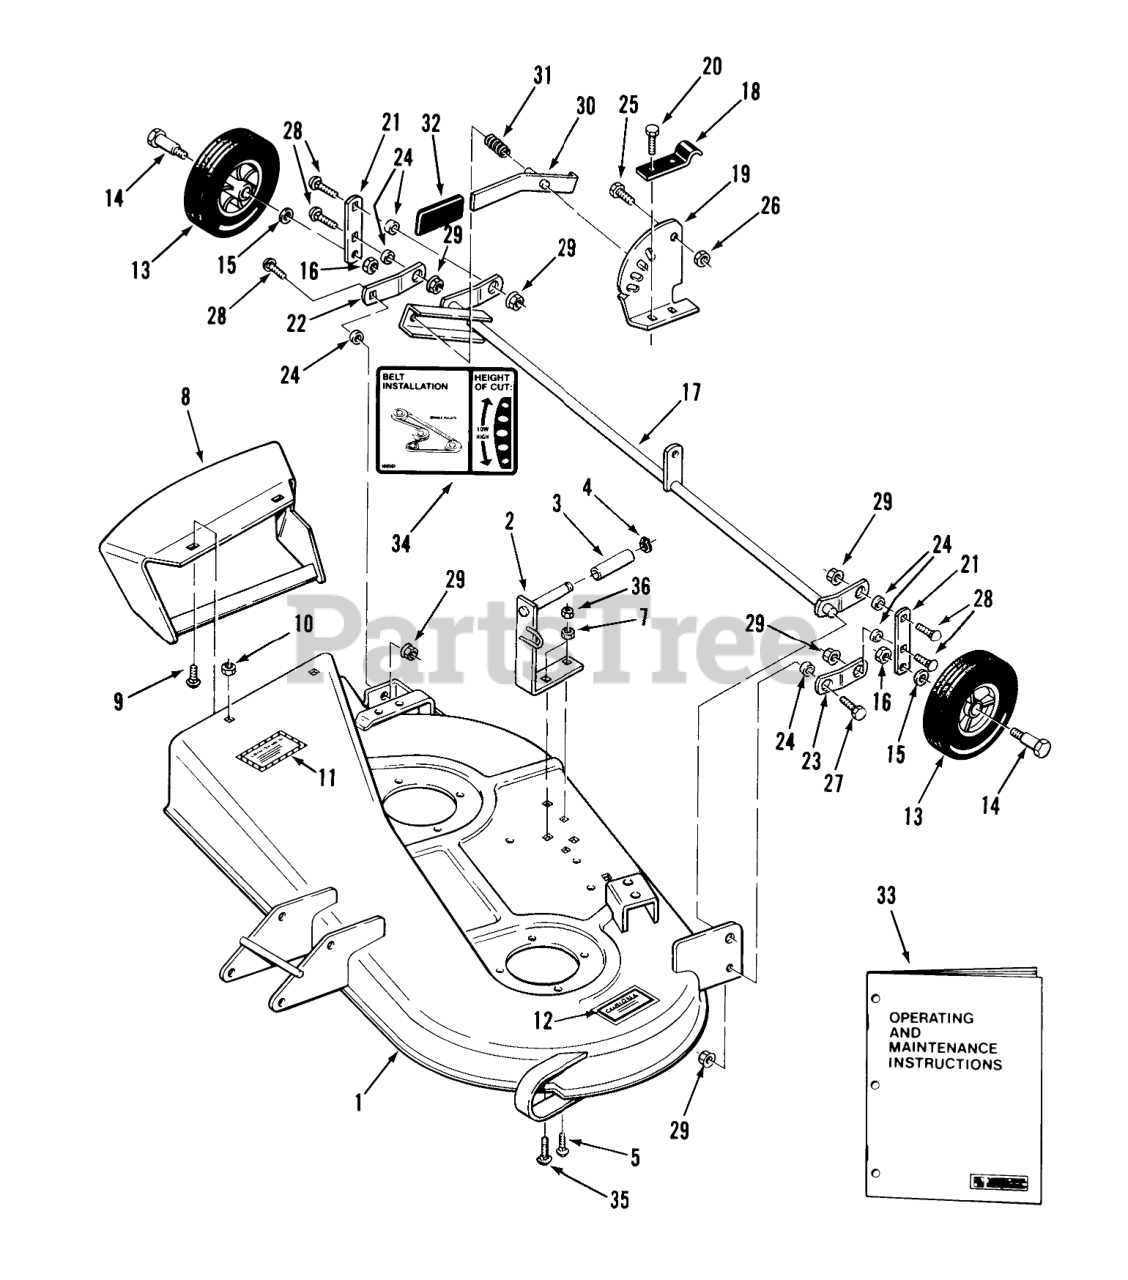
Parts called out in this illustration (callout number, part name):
1	ASSY 32" MOWER SI R
2	ASSY-BRACKET GUID R
3	SPACER
4	Snap Ring
5	CARRIAGE BOLT -9
7	Nut
8	ASSY-CHUTE EXT R
9	Bolt
10	Nut
11	DECAL
12	Caution Decal
13	WHEEL-GAUGE
15	WASHER
16	Nut
17	Gage Wheel Support
18	Bracket-Pivot
19	Quadrant
20	Bolt
21	LINK R
22	ARM-PIVOT RH R
23	Arm LH
24	SPACER
26	Nut
27	BOLT
28	Bolt
29	LOCKNUT-FLANGE
30	Lever
31	SPRING-COMPRESSION
33	Operating & Maintenance Instructions
34	DECAL-BELT&HEIGHT
35	Bolt-Carriage
36	Nut
